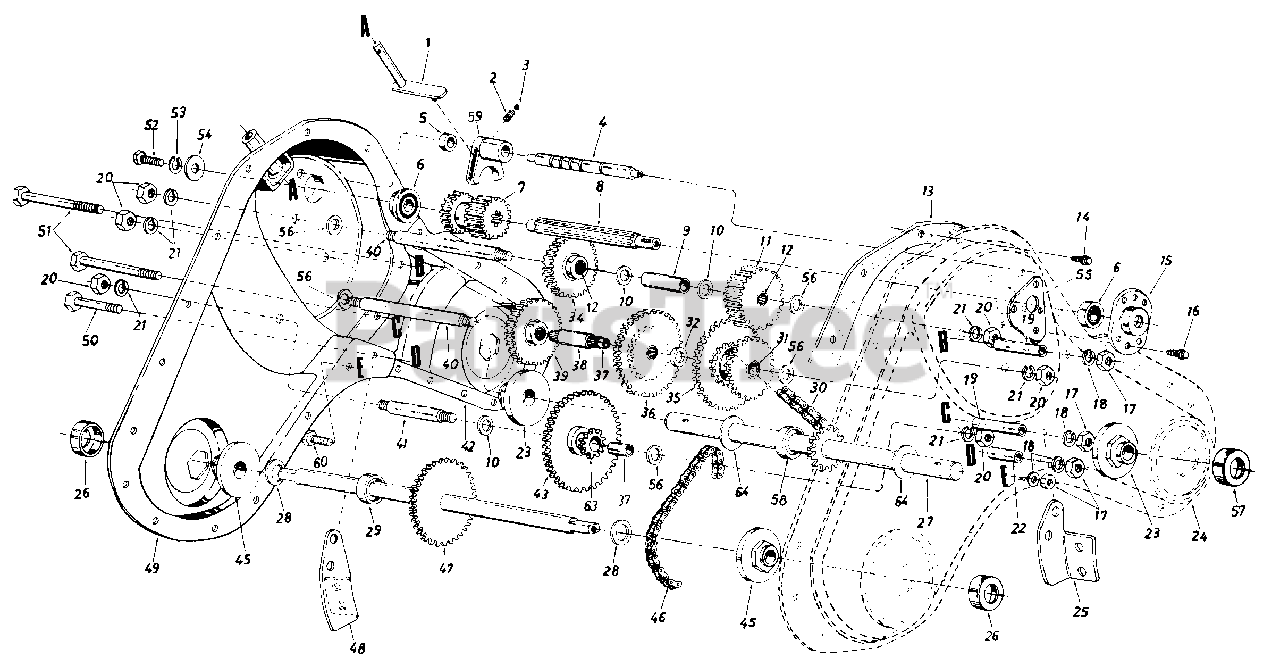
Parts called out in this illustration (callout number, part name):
1	Shifting Bracket Ass'y.
2	Compression Spring .50" Lg.
3	Ball Detent .250" Dia.
4	Detent Shaft 1/2" Dia.
5	Spacer .505" I.D. x .88" O.D.
6	Ball Brg. .62" I.D. x 1.38"
7	Spur Gear 16T (Input)
8	Input Spline Shaft 7/8
9	Spacer .657" I.D. x 2.85" Lg.
10	Fl-Wash. .640" I.D. x 1.24"
11	Spur Gear 30T 7/8" I.D.
12	Needle Bearing 5/8" I.D.
13	Gasket-Trans. Hsg.
14	Hex Wash. S-Tap Scr. 1/4-20 x.50" Lg.
15	1-3/8" Dia. Bearing Housing
16	Hex TT-Tap Scr. 1/4-20 x .75"
17	Hex Nut 5/16-18 Thd.
18	L-Wash. 5/16" I.D.*
19	Spacer 1.56" Lg.
20	Hex Nut 7/16-20 Thd.
21	Bell-Wash. .45" I.D. x 1.0"
22	Spacer 1.015" Lg.
23	Tine Shaft Brg. 1.002 x 2.50
24	Trans. Housing Ass'y.-L.H.
27	Tine Shaft Ass'y. 1.00" O.D.
28	Fl-Wash. .75" I.D. x 1.5" O.D
29	Spacer .75" I.D. x .50" Lg.
30	Chain #50 5/8 Pitch x 52 0 Links-Endless
31	Needle Bearing 5/8" I.D.
32	Fl-Wash. 5/8" I.D.
34	Spur Gear 30T 12/16" I.D.
35	30/44T Gear Ass'y. Comp.
36	Spur Gear 44T
37	Sleeve Bearing
38	Gear Hub 3/4" I.D. x 3.0" Lg.
39	Spur Gear 30T 1.0" I.D. x 1/2" W
40	Jack Shaft 5/8" Dia. x 5.0"
41	Jack Shaft 5/8" Dia. x 2.38"
42	Trans. Housing Ass'y.-R.H.
43	Spur Gear 55T
45	Wheel Brg. .752 x 2.50
46	#420 Chain 1/2 Pitch x 50 0 Links-Endless
47	Wheel Shaft Ass'y. 15.6"
51	Hex Bolt 5/16-18 x 2.50"*
52	Hex Bolt 1/4-20 x .62" Lg.
53	L-Wash. 3/8" I.D.
54	Fl-Wash. 1/4" I.D. x .93" O.D.
55	Gear Positioner Bracket
56	Fl-Wash. 7/16" I.D. x 1-3/8"
57	Dust Cover Ass'y. 1.0" Shaft
58	Spacer 1.0" I.D. x 2.0" O.D.
59	Shifting Fork
60	Hex Bolt 5/16-18 x .75" Lg.
63	10T Sprocket Ass'y.
64	Thrust Wash. 1.030" I.D. x 1.62" O.D.
